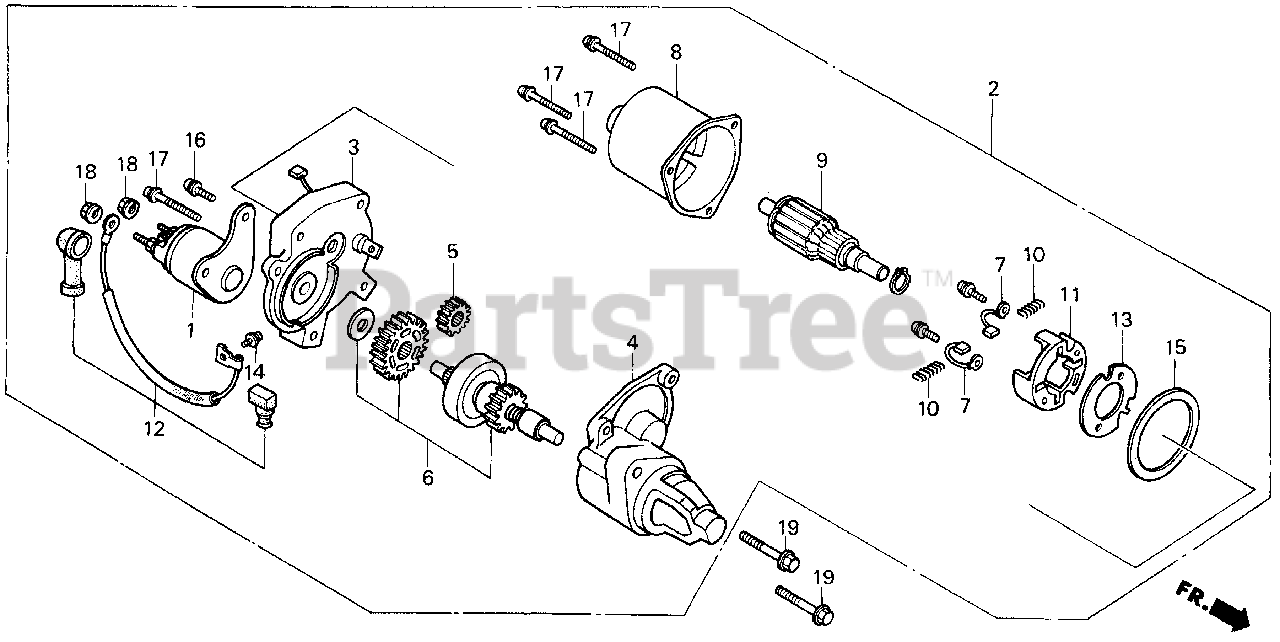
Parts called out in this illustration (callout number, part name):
1	CONTACTOR ASSY.
2	MOTOR UNIT, STARTER
3	BRACKET, CENTER
4	BRACKET, FR.
5	GEAR, DRIVE PINION
6	CLUTCH, OVERRUNNING
7	BRUSH
8	YOKE
9	ARMATURE
10	SPRING, BRUSH RETURN
11	HOLDER, BRUSH
12	WIRE, WATER COVER
13	INSULATOR
14	SCREW-WASHER (4X6)
15	GASKET
16	BOLT-WASHER (5X14)
16	SCREW-WASHER (5X14)
17	SCREW-WASHER (5X3)
18	NUT-WASHER (6MM)
19	BOLT, FLANGE (8X40)
